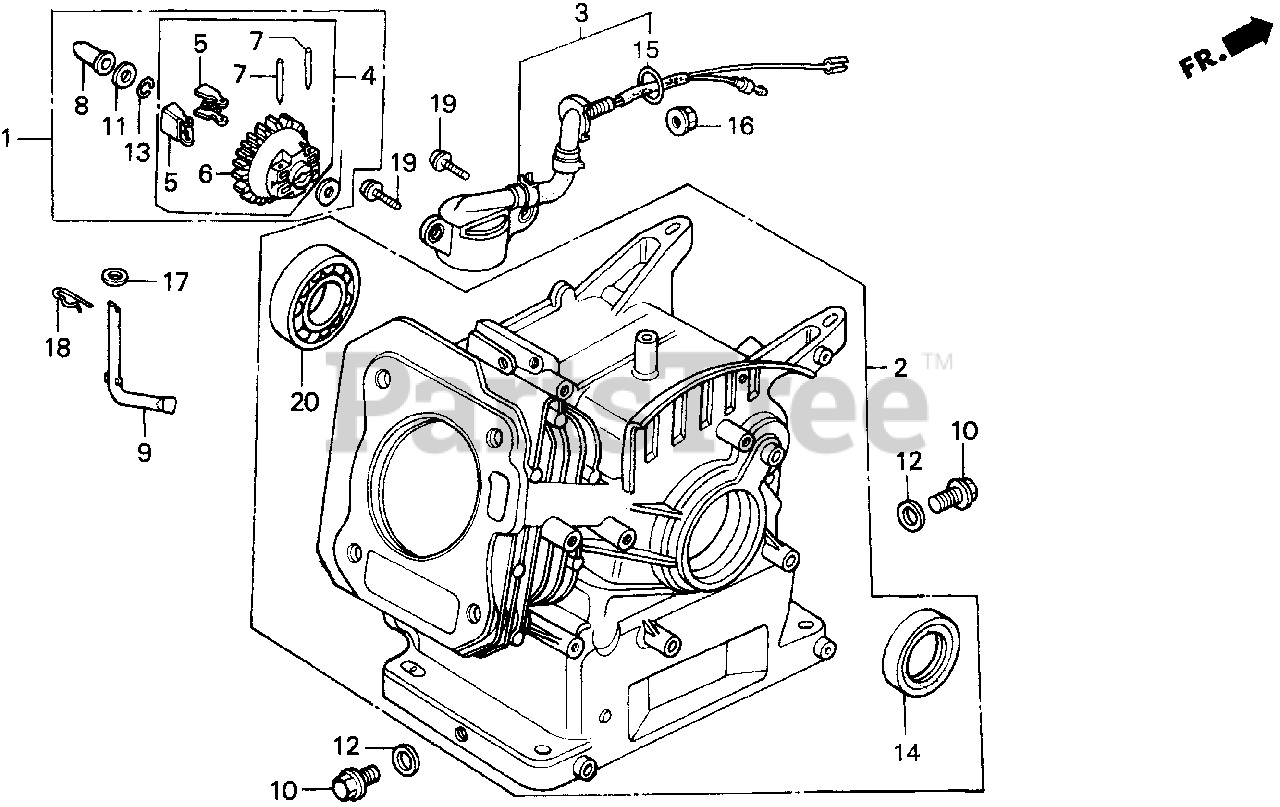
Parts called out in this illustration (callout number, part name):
1	GOVERNOR KIT
2	CYLINDER ASSY. (OIL ALERT)
3	SWITCH ASSY., OIL LEVEL
4	GOVERNOR ASSY.
5	WEIGHT, GOVERNOR
6	HOLDER, GOVERNOR WEIGHT
7	PIN, GOVERNOR WEIGHT
8	SLIDER, GOVERNOR
9	SHAFT, GOVERNOR ARM
10	BOLT, DRAIN PLUG
11	WASHER, THRUST (6MM)
12	WASHER, DRAIN PLUG (10.2MM)
13	CLIP, GOVERNOR HOLDER
14	OIL SEAL (25X41X6)
15	O-RING (13.5X1.5) (ARAI)
16	NUT, FLANGE (10MM)
17	WASHER, PLAIN (6MM)
18	PIN, LOCK (8MM)
19	BOLT, FLANGE (6X12)
20	BEARING, RADIAL BALL (6205)
